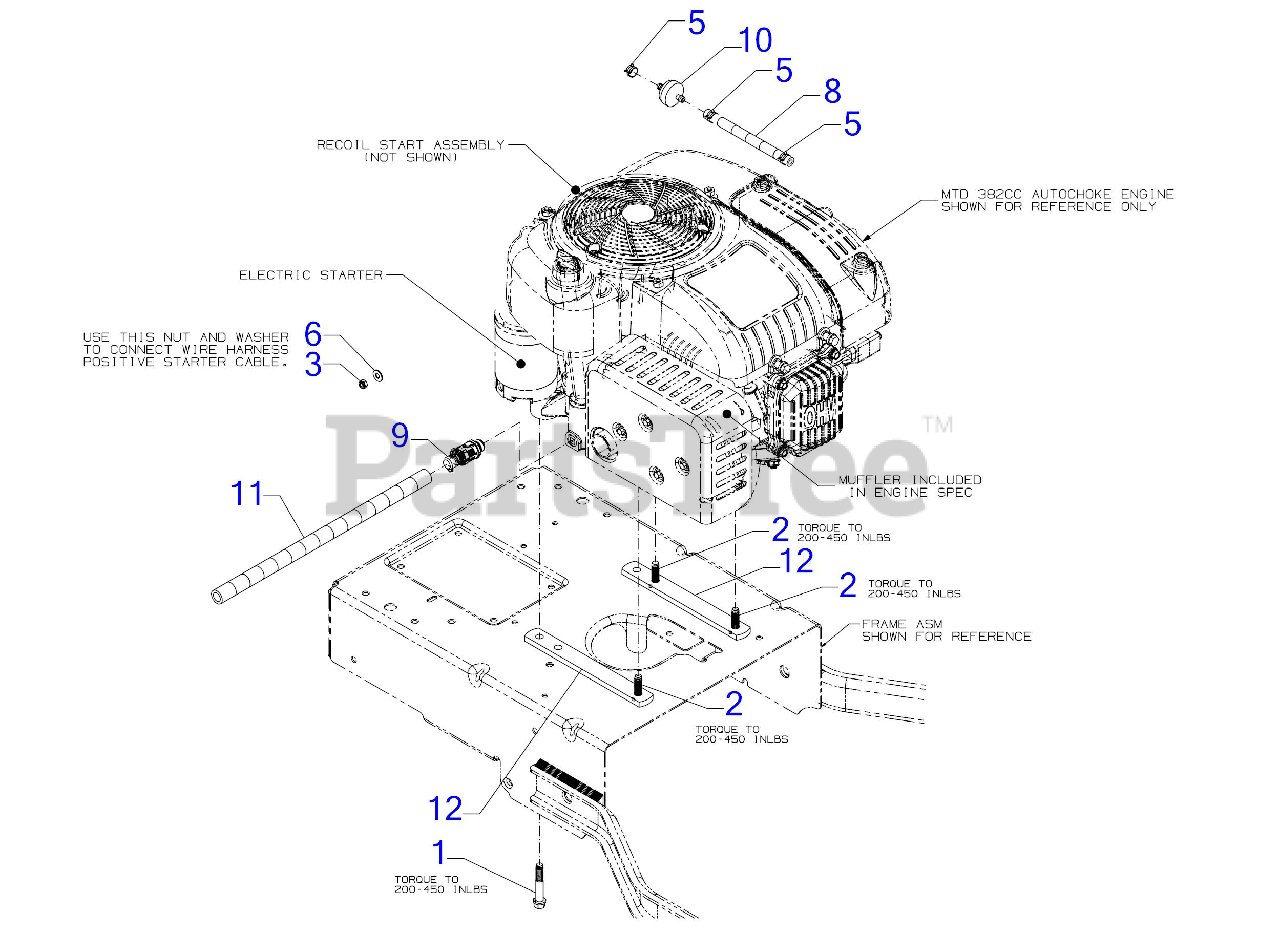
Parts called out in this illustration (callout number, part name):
1	SCREW 3/8-16 x 2.25
2	SCREW 3/8-16 x 1.500
3	HEX NUT
5	HOSE CLAMP 1/20
6	FLAT WASHER
8	FUEL HOSE LOW PERMEATION
9	OIL DRAIN VALVE
10	FUEL FILTER
11	DRAIN HOSE 14''
